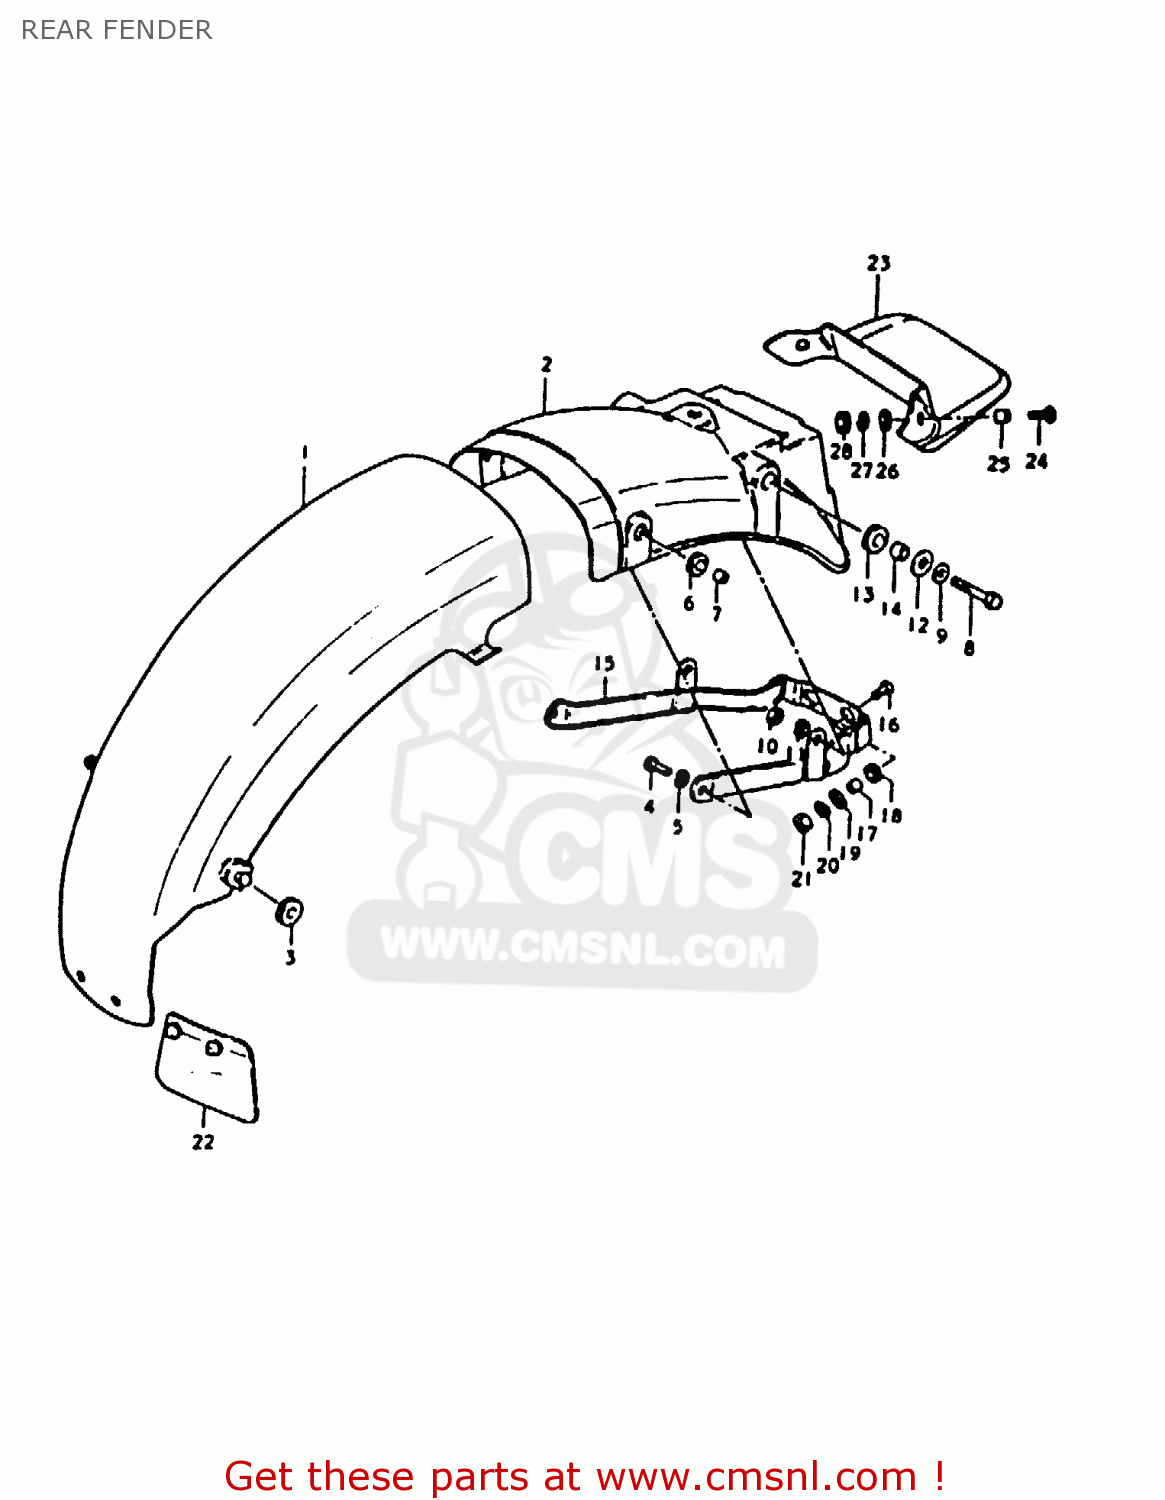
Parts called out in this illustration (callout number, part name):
1	FENDER,REAR
2	BODY,RR FENDER RR
3	CUSHION
4	BOLT
5	LOCK WASHER
6	CUSHION
7	SPACER(6.1X9X7.5)
8	BOLT
9	WASHER
10	NUT
11	LOCK WASHER
12	WASHER(8.5X26X1.2)
13	CUSHION
14	SPACER (8.2X12X7.5)
15	REINFORCEMENT,REAR FENDER
16	SCREW
17	SPACER (6.1X9X9)
18	CUSHION
19	WASHER(6,5X22X1.6)
20	LOCK WASHER
21	NUT
22	GUIDE,RR FENDER MUD
23	EXTENSION,REAR FENDER
24	SCREW (6X15)
25	SPACER(6.2X8.3X5.7)
26	WASHER(6.5X18X1)
27	LOCK WASHER
28	NUT
